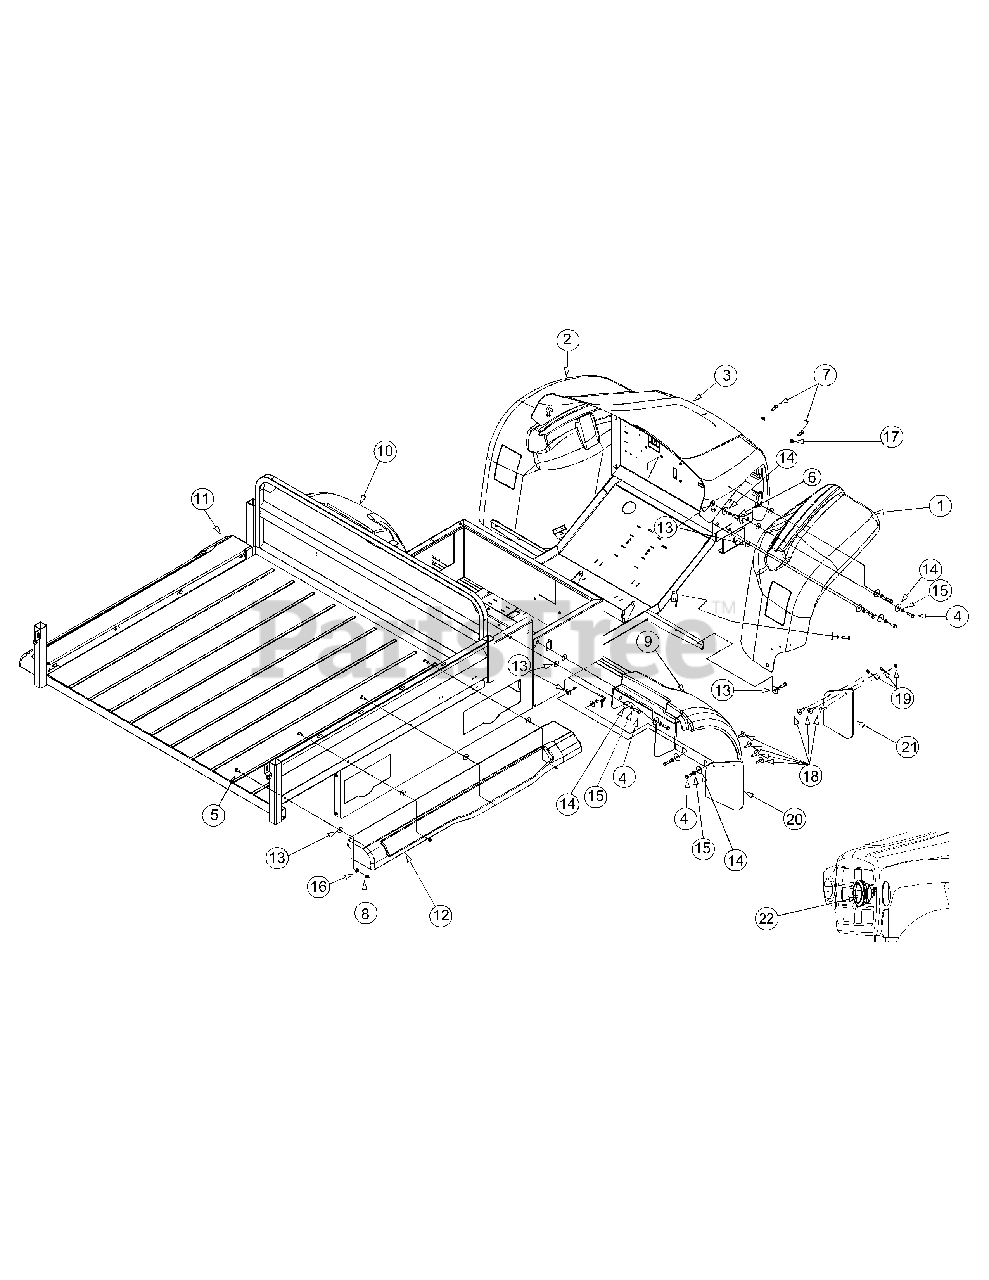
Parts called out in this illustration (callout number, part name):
1	Front Fender Panel, RH
2	Front Fender Panel, LH
3	Hood Panel
4	Hex Screw, 5/16-18 x 1.0 Gr5
5	Hex Screw, 1/4-20 x .75
6	Thumb Adjust Screw, 5/16-18 x 1.0
7	Hex Screw, 1/4-20
8	Nylon Hex Lock Nut, 1/4-20
9	Rear Fender Panel, RH
10	Rear Fender Panel, LH
11	Bed Skirt Panel, LH
12	Bed Skirt Panel, RH
13	Rubber Washer, .310 x 1.0 x .125
14	Flat Washer, .350 x 1.25 x .06
15	Lock Washer, 5/16
16	Flat Washer, .271 x .630 x .065
17	Flat Washer, .344 x .688 x .0652
18	Pop Rivet .188 Dia
19	Flat Washer, .194 x .62 OD x .063
20	Rear Mud Flap
21	Front Mud Flap
22	Headlight Assembly
